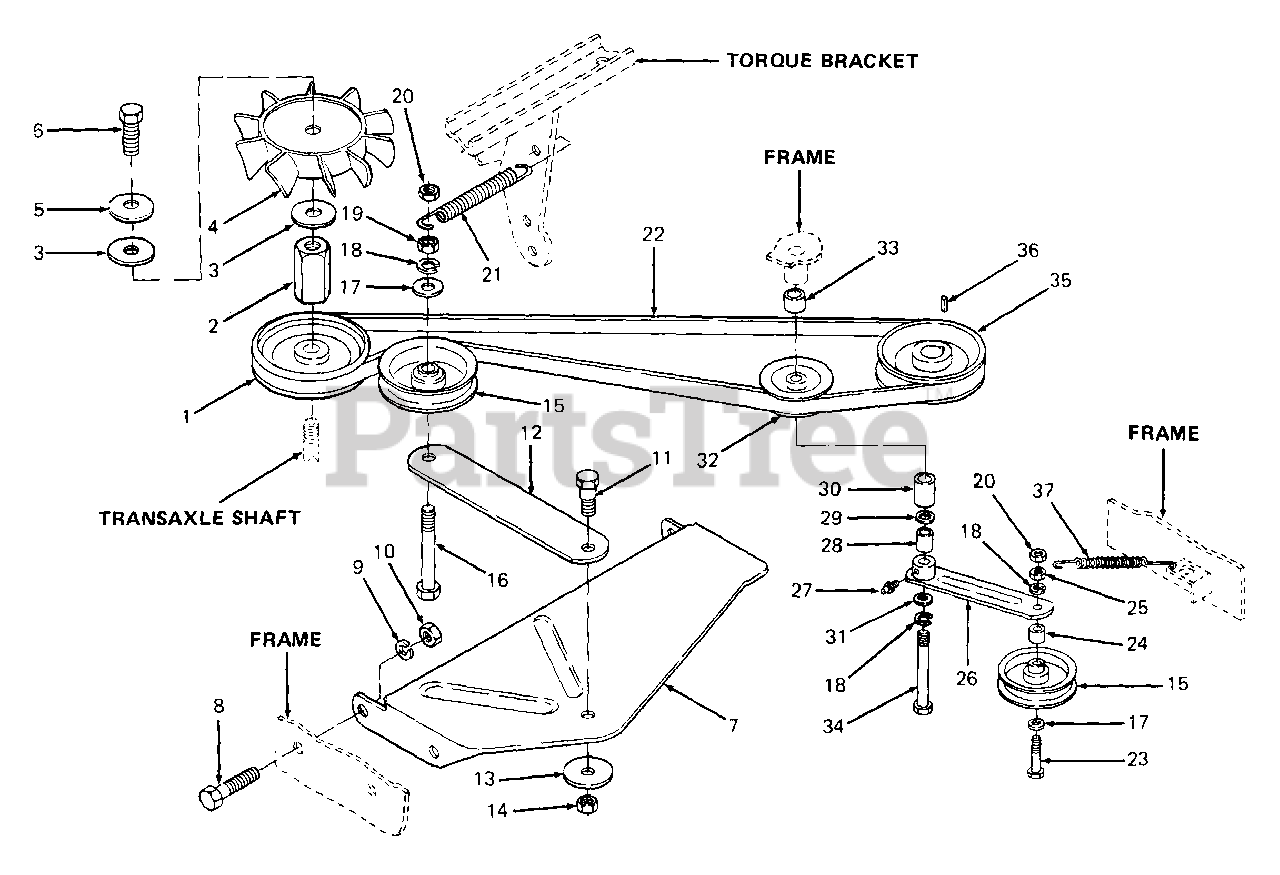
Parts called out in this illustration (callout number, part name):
1	V-Pulley, 4.0 Dia
2	Adapter, Fan, 1.0 Lg
3	Washer, Flat, .531 X 1.5 X .120 Thk
4	Fan, 10 Blade Hydro
5	Washer, Bell, .505 X 1.00 X .075
6	Bolt, Hex, 1/2-20 X .75 Lg GR5
7	Bracket, Clutch Mounting
8	Screw, Hex Cap, 5/16-18 X .62 Lg
9	Washer, Lock, 5/16
10	Nut, Hex, 5/16-18 GR5
11	Screw, Shoulder
14	Nut, Hex Center Lock, 5/16-18 GR5
15	Idler, Flat, 2.75 Dia
16	Screw, Hex Cap, 3/8-16 X 2.25 Lg GR5
17	Washer, Flat, .406 X .75 X .063 Thk
18	Washer, Lock, 3/8
19	Nut, Hex, 3/8-16 GR5
20	Nut, Hex Center Lock Jam, 3/8-16
21	Spring, Extension
22	V-Belt, A Sec X 80 in. Lg
23	Screw, Hex Cap, 3/8-16 X 2.75 Lg GR5
24	Spacer, .375 X .625 X .445 Lg
25	Nut, Hex Jam, 3/8-16 GR5
27	Fitting, Lube, 3/16 Drive
28	Spacer, .3775 X .600 X .830 Lg
29	Washer, Flat, .385 X .87 X .06 Thk Hdn
30	Spacer, .38 X .75 X 1.26 Lg
31	Washer, Flat, .406 X 1.25 X .157 Thk
32	V-Idler, 2.62 OD
33	Bushing, .39 X 1.O X .812 Lg
34	Bolt, Hex, 3/8-16 X 4.75 Lg GR5
35	Pulley, Engine, 3.5 Dia
36	Key, Square, 1/4 X .75 Lg
37	Spring, Extension
